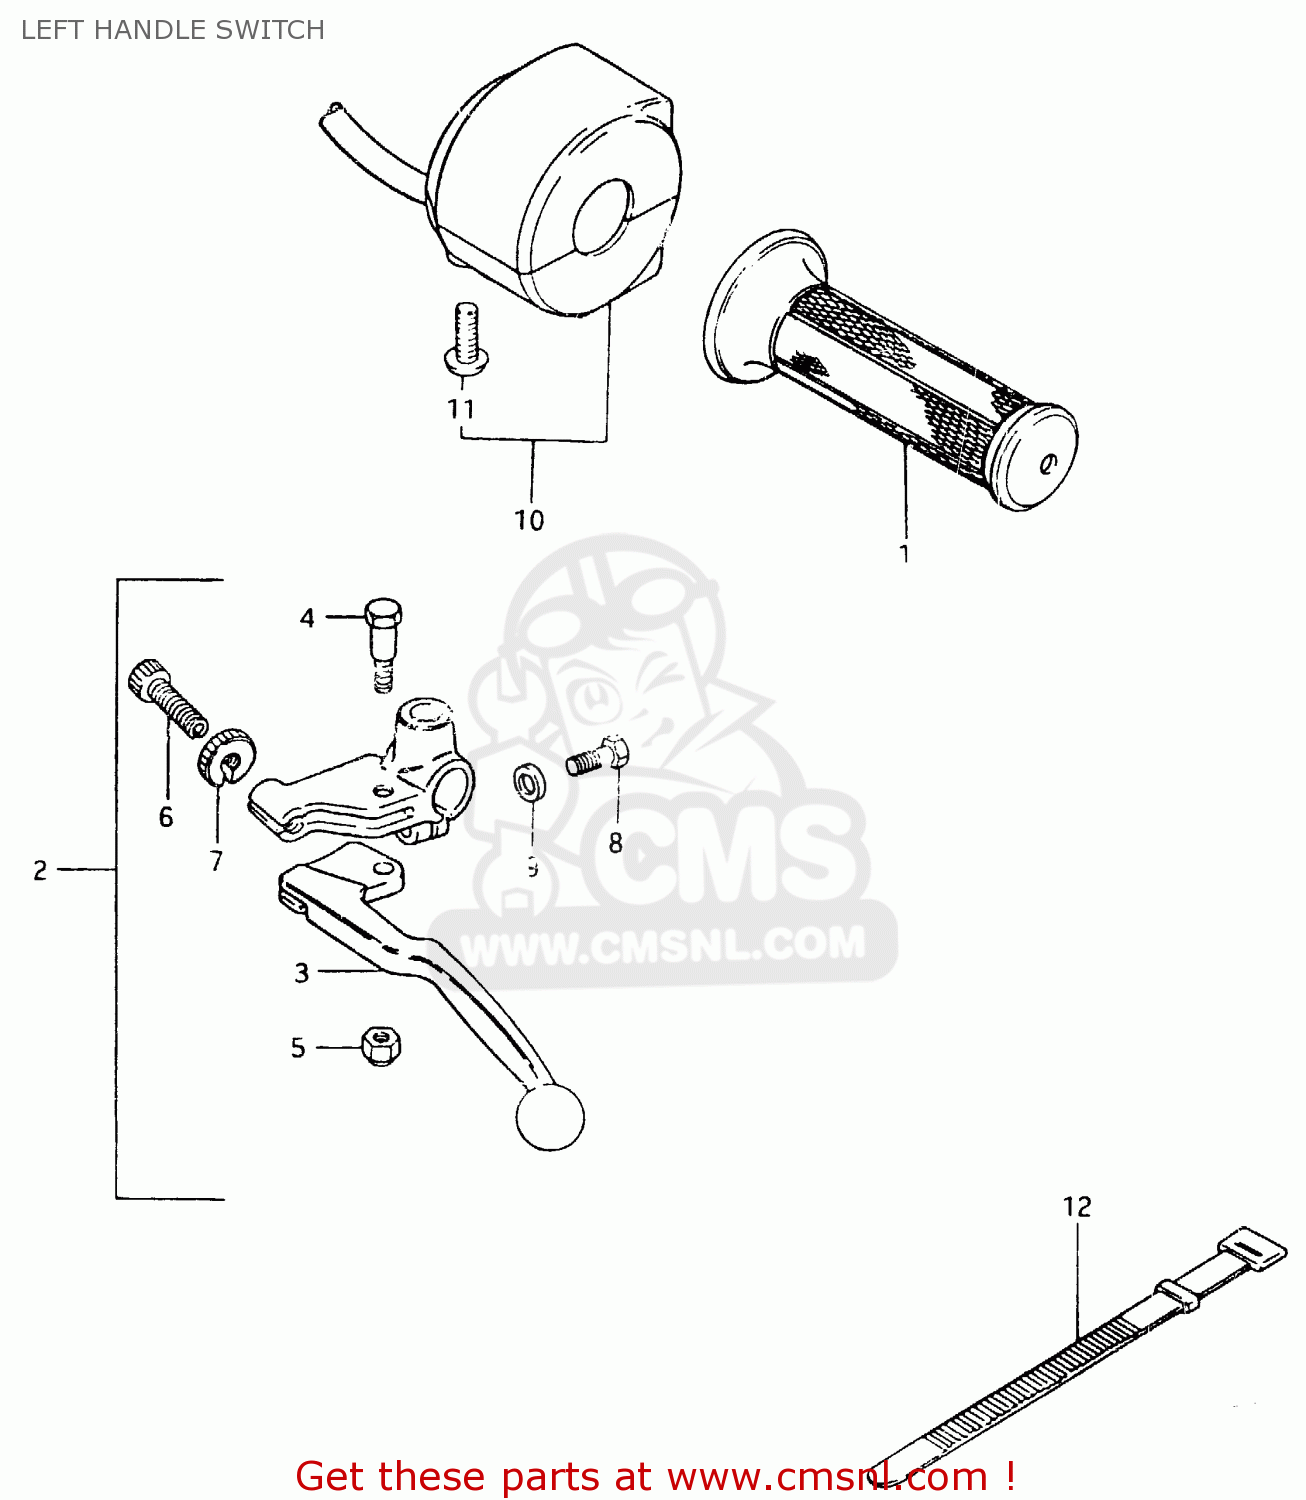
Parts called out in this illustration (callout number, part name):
1	GRIP,L
2	LEVER ASSY, CLUTCH
3	LEVER,CLUTCH
4	BOLT,LEVER
5	NUT 6MM
6	ADJUSTER,CABLE
7	NUT,CABLE ADJUSTER
8	BOLT,CLUTCH LEVER HOLDER
9	SPACER
10	SWITCH ASSY, HANDLE LH
11	SCREW
12	CLAMP(L:120)
